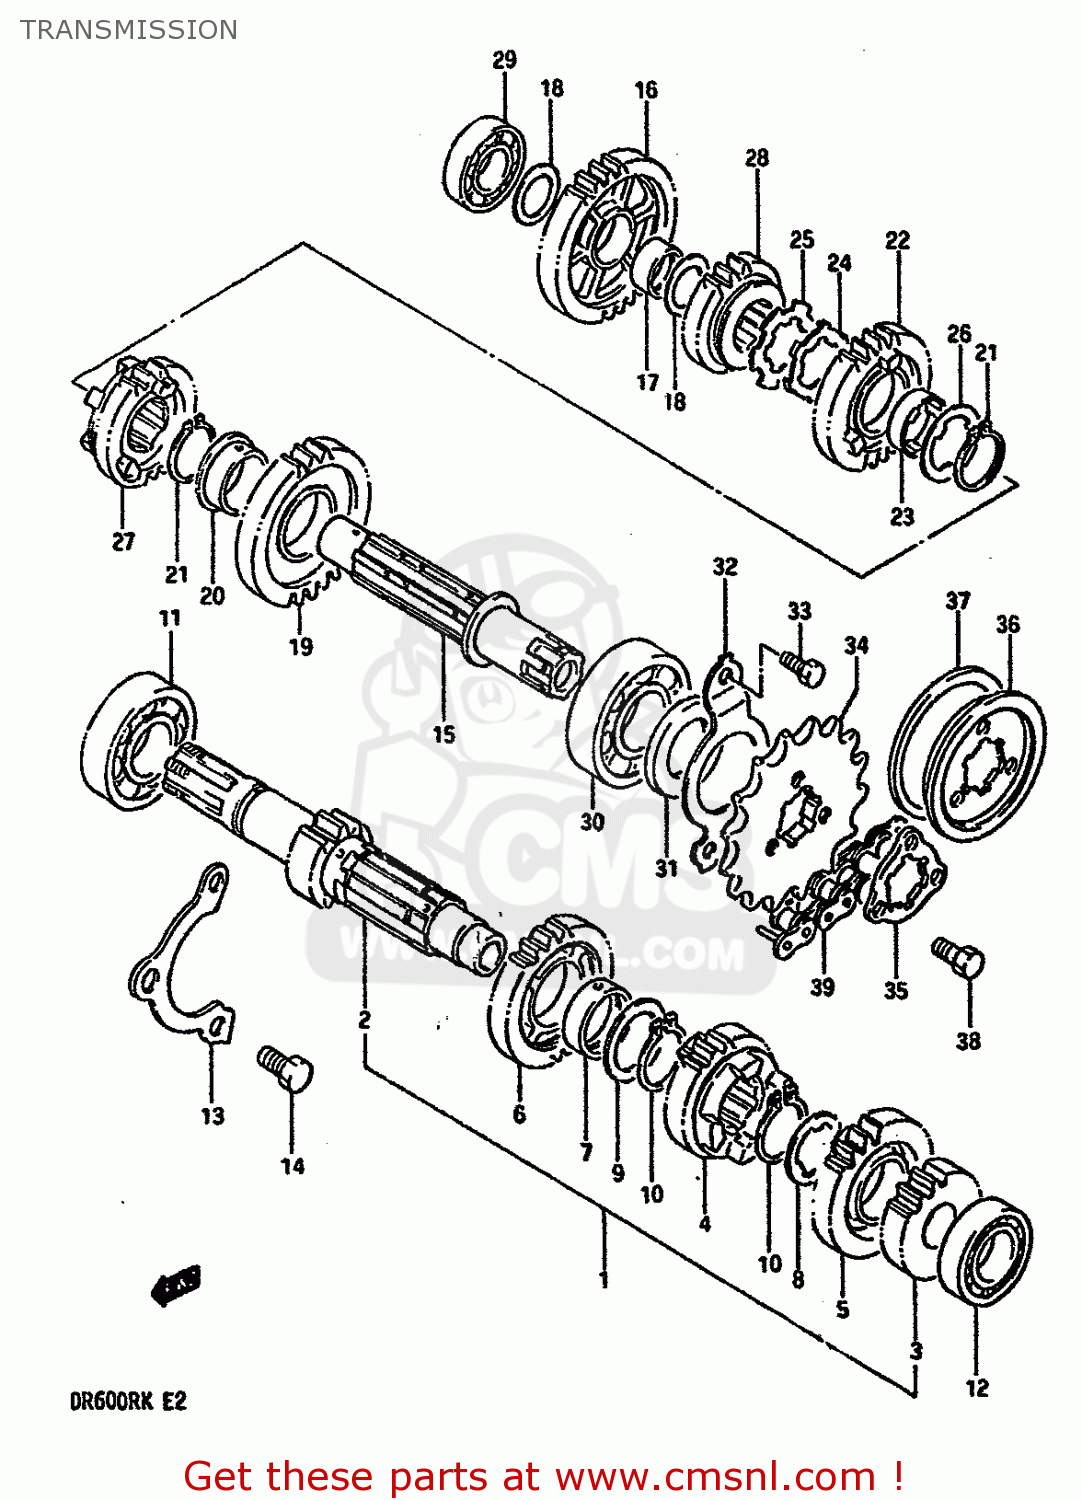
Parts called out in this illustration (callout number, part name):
1	SHAFT ASSEMBLY,COUNTER
2	SHAFT,COUNTER
3	GEAR,SECOND DRIVE
4	GEAR,THIRD/FOURTH DRIVE (NT:
5	GEAR,FOURTH DRIVE
6	GEAR,5TH DRIVE
7	BUSHING 25X29X10
8	WASHER,LOCK
9	WASHER
10	RING,SNAP
11	BEARING
12	BEARING
13	RETAINER,CNTR SHAFT BEARING
14	BOLT, 8X1.25X1
15	SHAFT,DRIVE
16	GEAR,FIRST DRIVEN
17	BUSH(20X24X13)
18	WASHER
19	GEAR,2ND DRIVEN
20	BUSH
21	RING,SNAP
22	GEAR,THIRD DRIVEN
23	BUSHING
24	WASHER
25	WASHER,LOCK
26	WASHER,LOCK
27	GEAR,FOURTH DRIVEN
28	GEAR,FIFTH DRIVEN
29	BEARING(20X42X12)
30	BEARING(25X62X17)
31	SEAL,OIL(25X45X5)
32	RETAINER,DRIVESHAFT O
33	BOLT
34	SPROCKET,ENGINE(NT:16)
35	PLATE,ENGINE SPROCKET
36	PLATE,ENGINE SPROCKET
37	DAMPER,ENGIN SPROCKET
38	BOLT(6X13)
39	CHAIN ASSEMBLY,DRIVE
